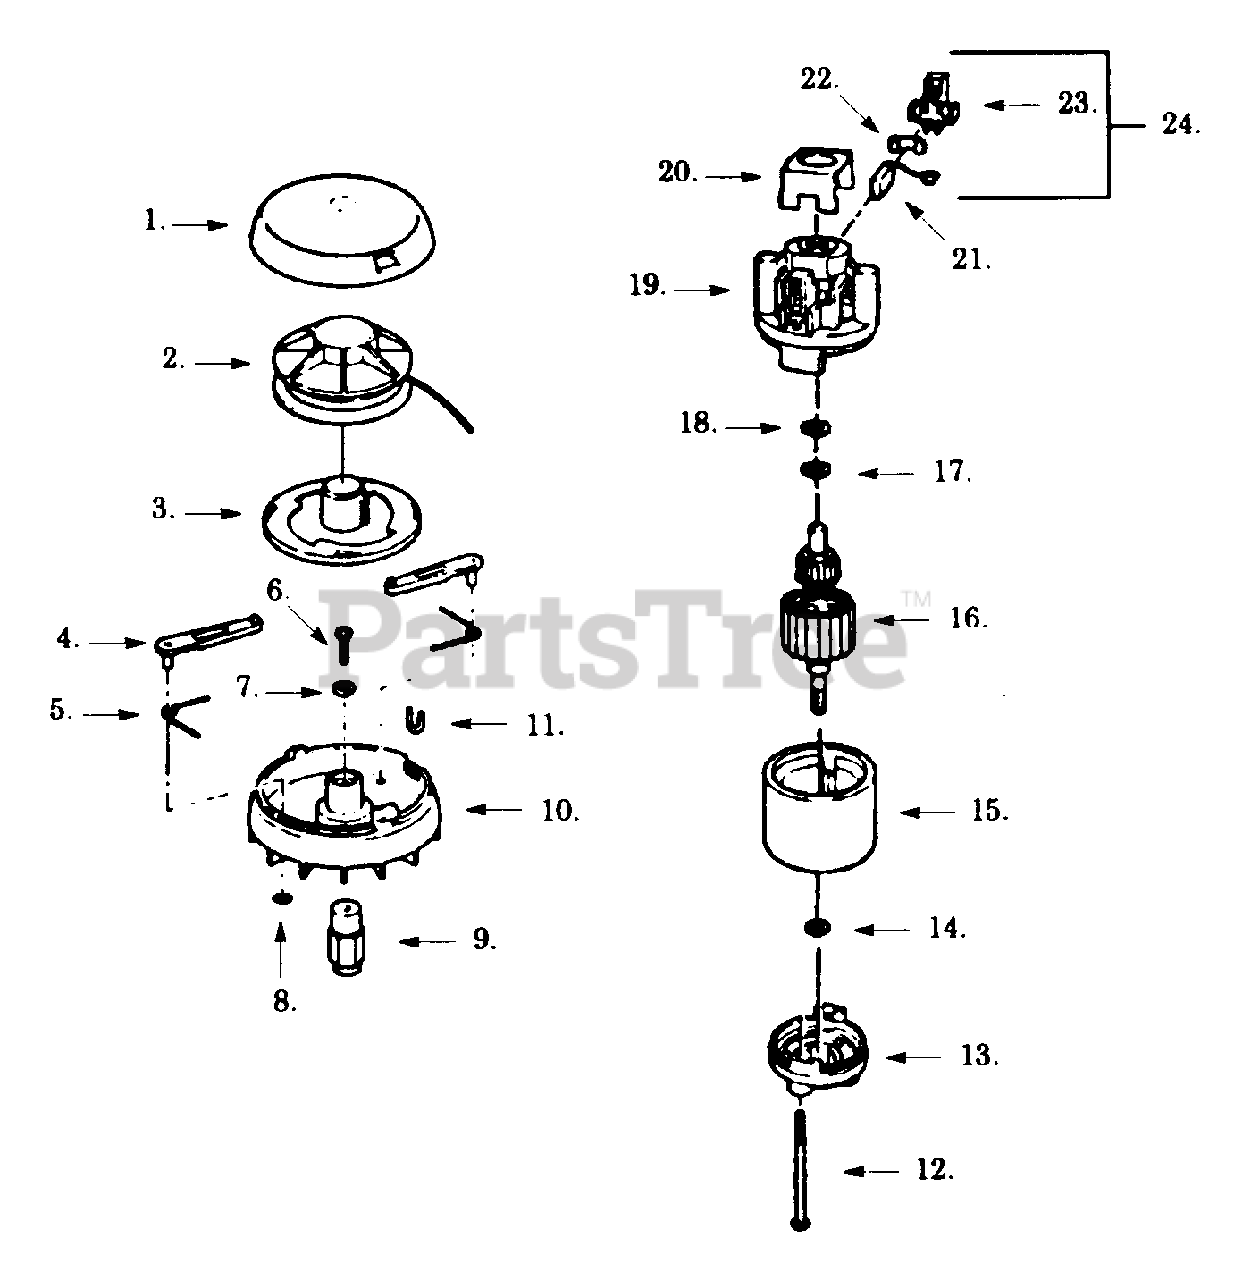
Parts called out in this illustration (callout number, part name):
2	Spool & Line
8	Push Nut
9	Drive Adapter
10	Housing Head
11	Line Shield
13	Endbell Ass'y. (Drive)
15	Field Ass'y.
16	Armature Ass'y.
19	Endbell Ass'y. (Brush)
20	Insulator
22	Brush Spring
23	Brush Holder
24	Brush Kit (Incl. 21,22,23)
